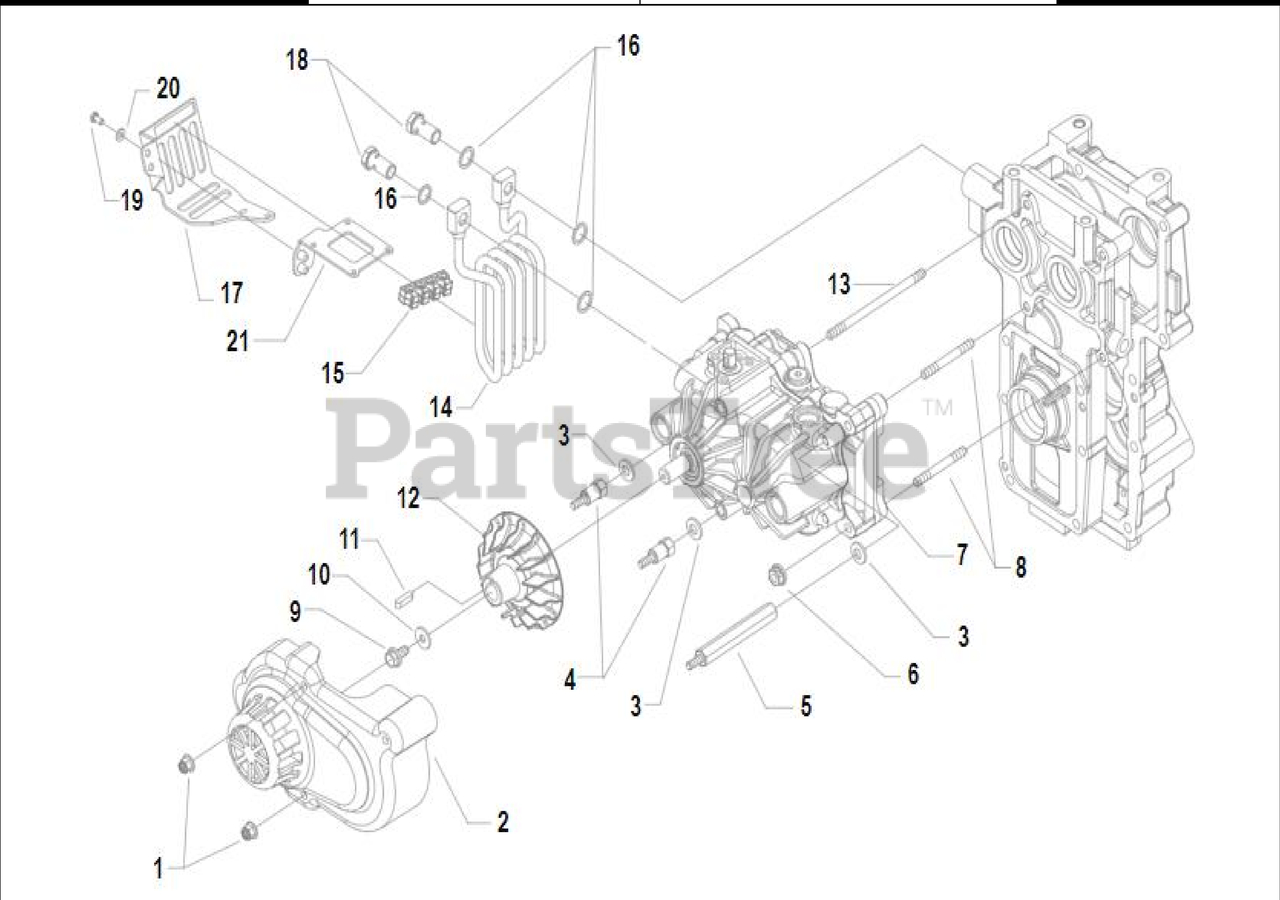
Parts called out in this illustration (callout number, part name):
1	SELFLOCK M6 FL NY DIN 6926
2	COVER
4	SHORT COLUMN
5	LONG COLUMN
6	SELFLOCK NUT M8 6S
7	KANZAKI PUMP ASSEMBLY (KHS-13JH)
8	STUD BOLT
9	SCREW M6X12
10	WASHER 6,6x18
11	KEY 5X5X20
12	FAN
13	STUD BOLT
14	RADIATOR
15	DAMPENER
16	COPPER WASHER 16,7x22/1,5
17	RADIATOR SHIELD
18	PIPE FITTING
19	SCREW TE M10X20 UNI 5739
20	WASHER M10 DIN 679
21	SHEILD SUPPORT BRACKET
